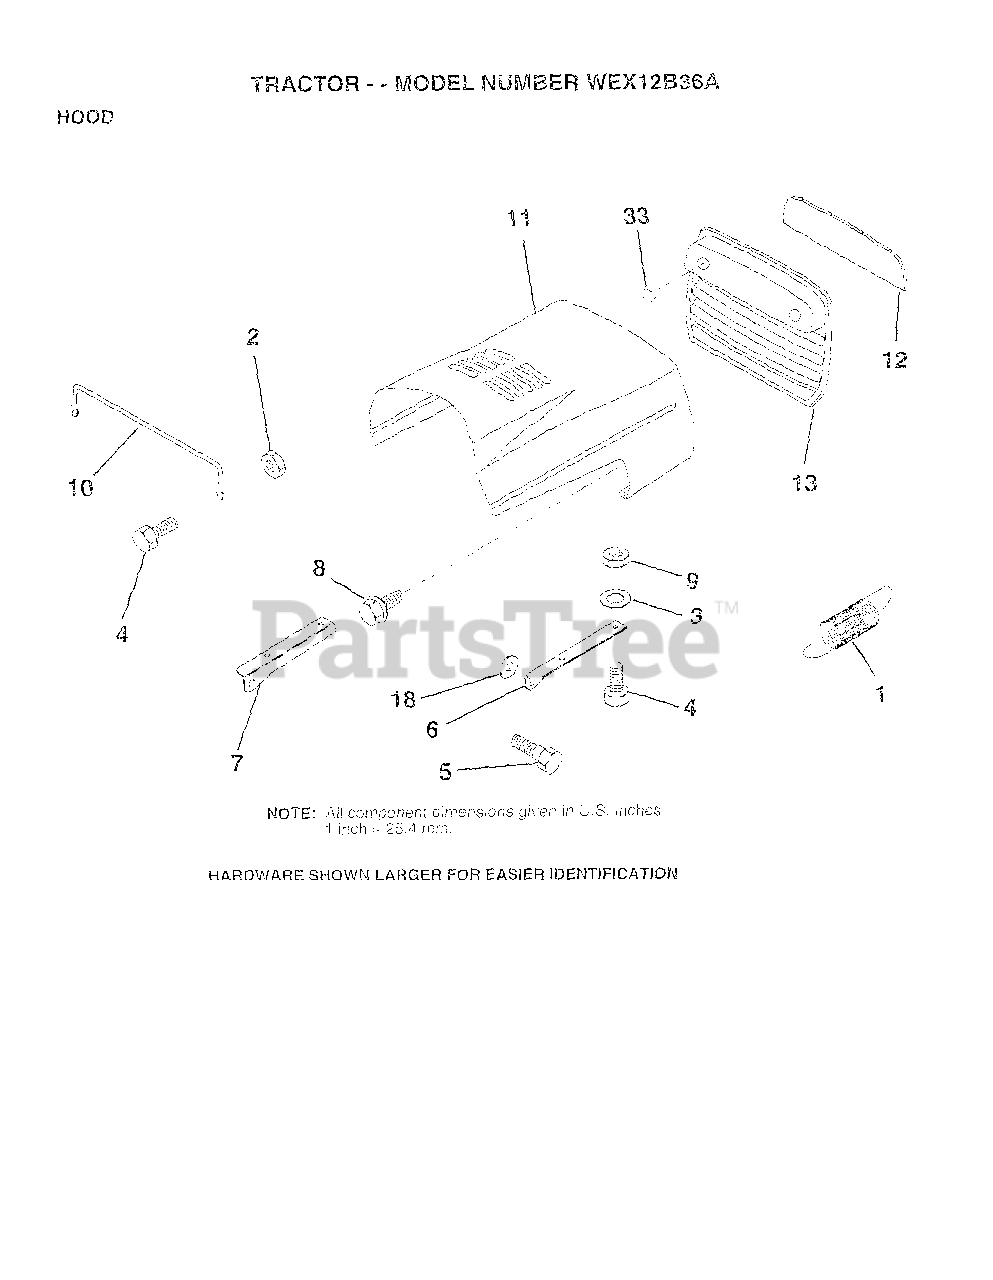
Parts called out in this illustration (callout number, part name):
1	EXT SPRING
2	NUT
3	WASHER
5	BOLT.SHLD.5/16-18
6	BRKT HOOD RH
7	BRKT HOOD LH
8	SCREW SLTD HXHD
9	NUT
10	"BRACE,HOOD"
11	HOOD.IMPREG.MS550
12	LENS
13	GRILL
18	WASHER
